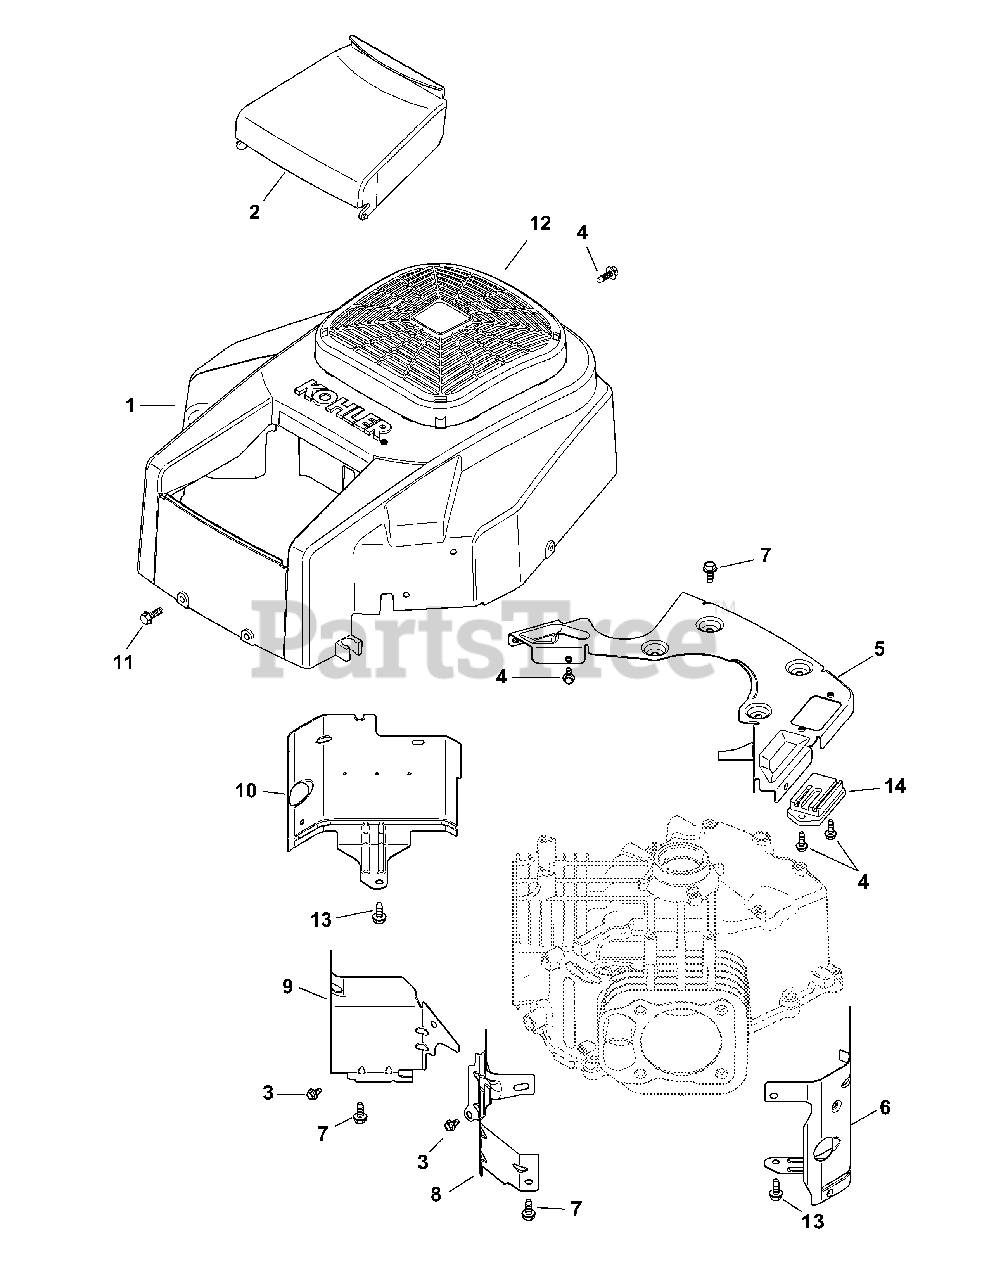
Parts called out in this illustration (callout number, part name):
1	Blower Housing Kit
2	Air Cleaner Cover
3	Flange Screw, M5 x .8 x 10
4	Flange Screw, M5 x .8 x 16
5	Backing Plate Kit
6	Cylinder Barrel Baffle, #2 Side
7	Flange Screw, M6 x 1.0 x 16
8	Valley Baffle, #2 Cylinder
9	Valley Baffle, #1 Cylinder
10	Cylinder Barrel Baffle, #1 Side
11	Screw, M6 x 1.7 x 18
13	Flange Screw, M6 x 1.0 x 10
14	Regulator/Rectifier
